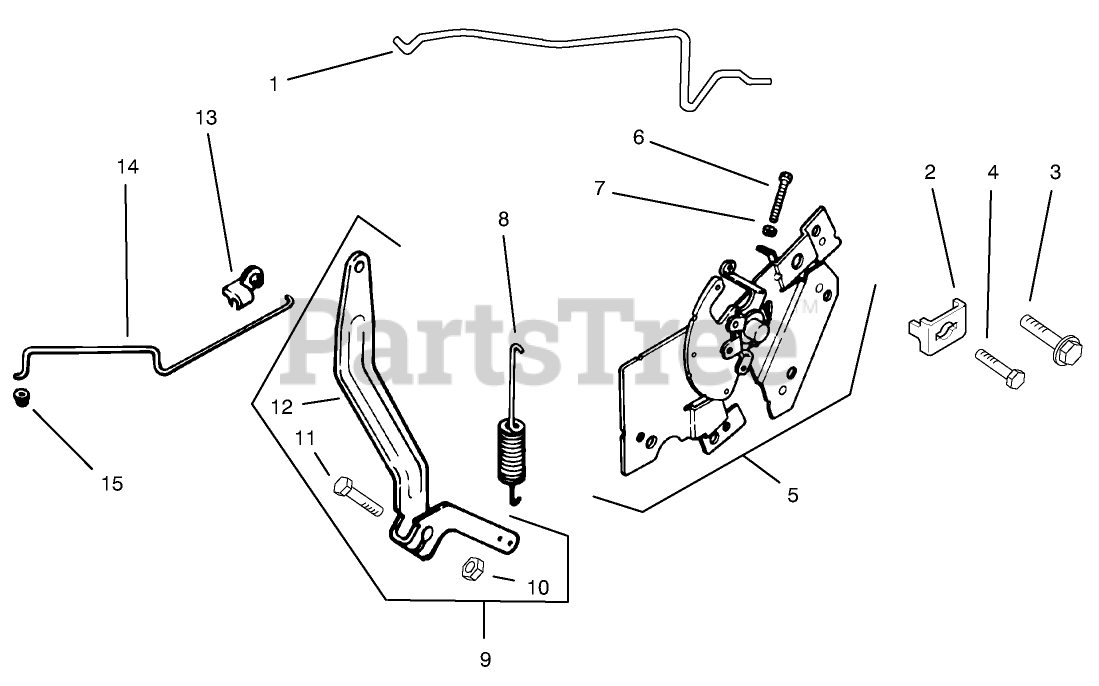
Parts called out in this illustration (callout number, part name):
1	Linkage-Choke
2	CLAMP-CABLE
3	SCREW-FLANGE, THREAD FORMING (M5X0.8X16)
4	Screw-Socket, 6 Lobed (Thread Forming, M6x1.0x20)
5	Control- Speed ASM (Incl 6,7)
6	Screw (M4x0.7x30)
7	NUT (M4X0.7)
8	Spring-Governor
9	Kit, Governor Lever (Incl 10-12)
10	Nut-Flange, Hex (1/4-20)
11	Bolt-Square Neck, Round Head (1/4-20x1)
12	Lever-Governor
13	BUSHING-RETAINING, LINKAGE
14	Linkage-Throttle
15	BUSHING-LINKAGE, THROTTLE
